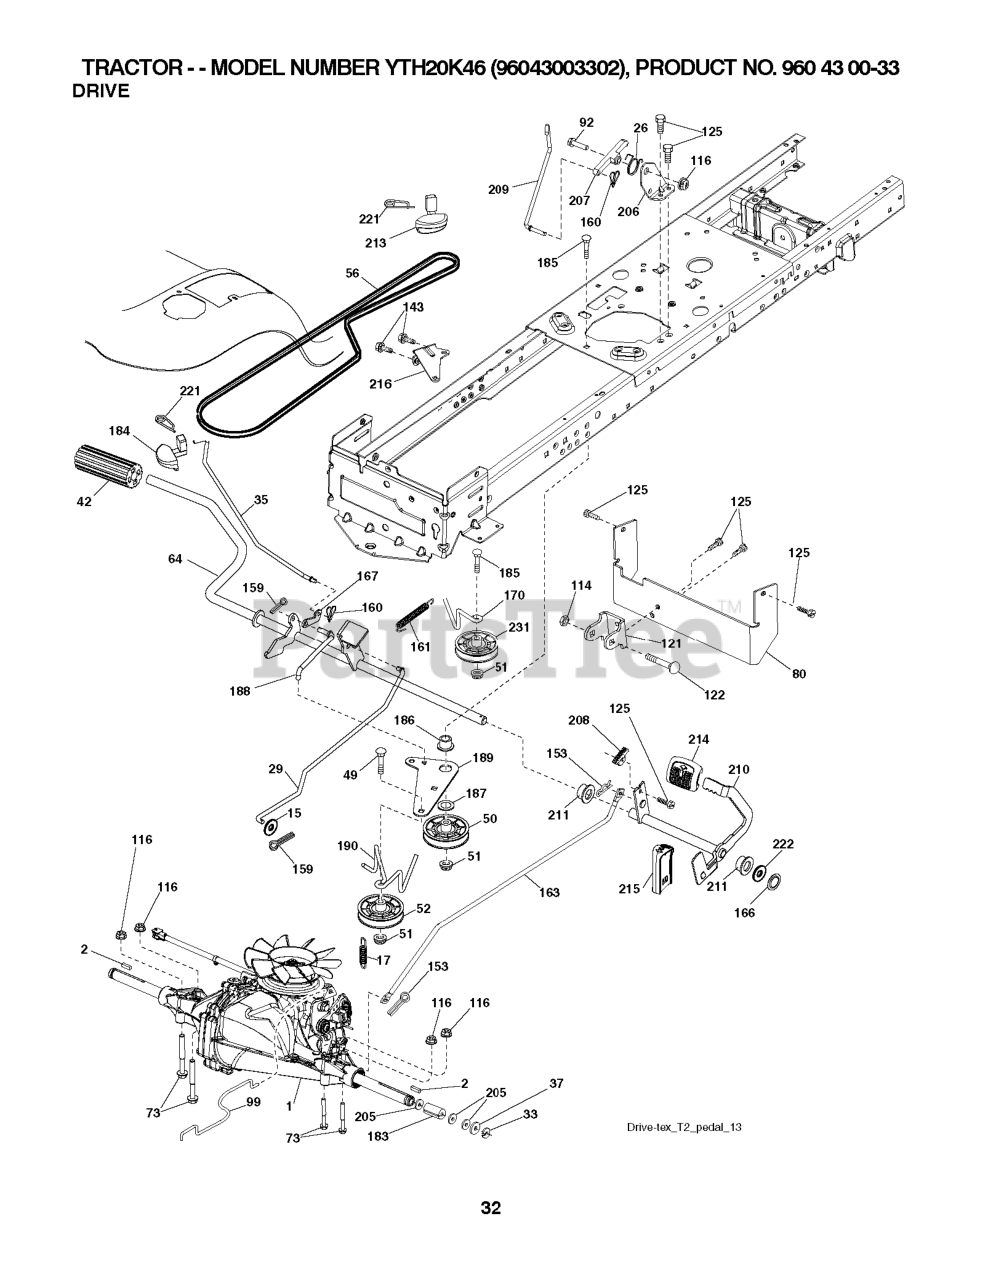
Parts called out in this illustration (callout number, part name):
2	SQUARE KEY
15	WASHER
17	SPRING.BRAKE.HG3000/3500
26	SPRING.RETURN.CRUISE
29	ROD.BRAKE.T2.TEX
35	ROD.BRAKE.PARKING.GT.H
42	PEDAL COVER T
50	IDLER.FLAT.910.OFFSET
51	NUT LOCK FLG 3/8-16 UNC
52	IDLER.V-GROOVE.910.OFFSET
64	SHAFT.ASM.PEDAL.BRK.CNTR
73	BOLT HEX 5/16-18 GR 5
80	RP.STRAP.TORQUE.FS.T2
92	BOLT
99	ROD.ASM.BYPASS.SPRING.T2.FS
114	NUT.71038.31-18.HEX.NYLOCK
116	NUT LOCK HEX FLANGE 5/16-18
121	BRACKET STRAP TORQUE
122	BOLT.5/16-18X2.5
125	SCREW
143	Screw 5/16-18 x 1/2 Hex, Self Tapping 5/16-18 x 1/2
153	RETAINER M
159	COTTER PIN
160	RETAINER CLIP
161	SPRING, RETURN LT
163	ROD.CONTROL.PCH.T2.TEX
166	NUT.PUSH.625.2006
167	LATCH.BRAKE.SPRING
170	KEEPER.CENTER SPAN.1.688
183	SPACER, AXLE PVST
184	HANDLE.PARKG.BRK.HUSQ X667
186	SPACER.RETAINER
187	WASHER 12/32X2X10GA
188	RP.LINK.CLUTCH.GROUND.DRIVE
189	BELLCRANK.GROUND.DRIVE.TEX.
190	KEEPER.BELLCRANK.DRIVE
206	BRKT.MOUNT.LATCH.CRUIS
207	LATCH.CONTROL.CRUISE
208	GEAR.SECTOR.CONTROL.CR
209	ROD.CONTROL.CRUISE.GT.
210	ROCKER.ASM.PEDAL.CONTR
211	BEARING.NYLON
213	KNOB.CONTROL.CRUSIE.HU
214	PEDAL.FORWARD.TEX.GT.4
215	PEDAL.REVERSE.TEX.GT.4
216	BRACKET.PULLEY.IDLER.W/TEX
221	RETAINER.SPRING.CLIP.H
222	WASHER 21/32 X 1-1/4 X 10 GA.
231	IDLER.V-GROOVE.1.688.OFFSET
